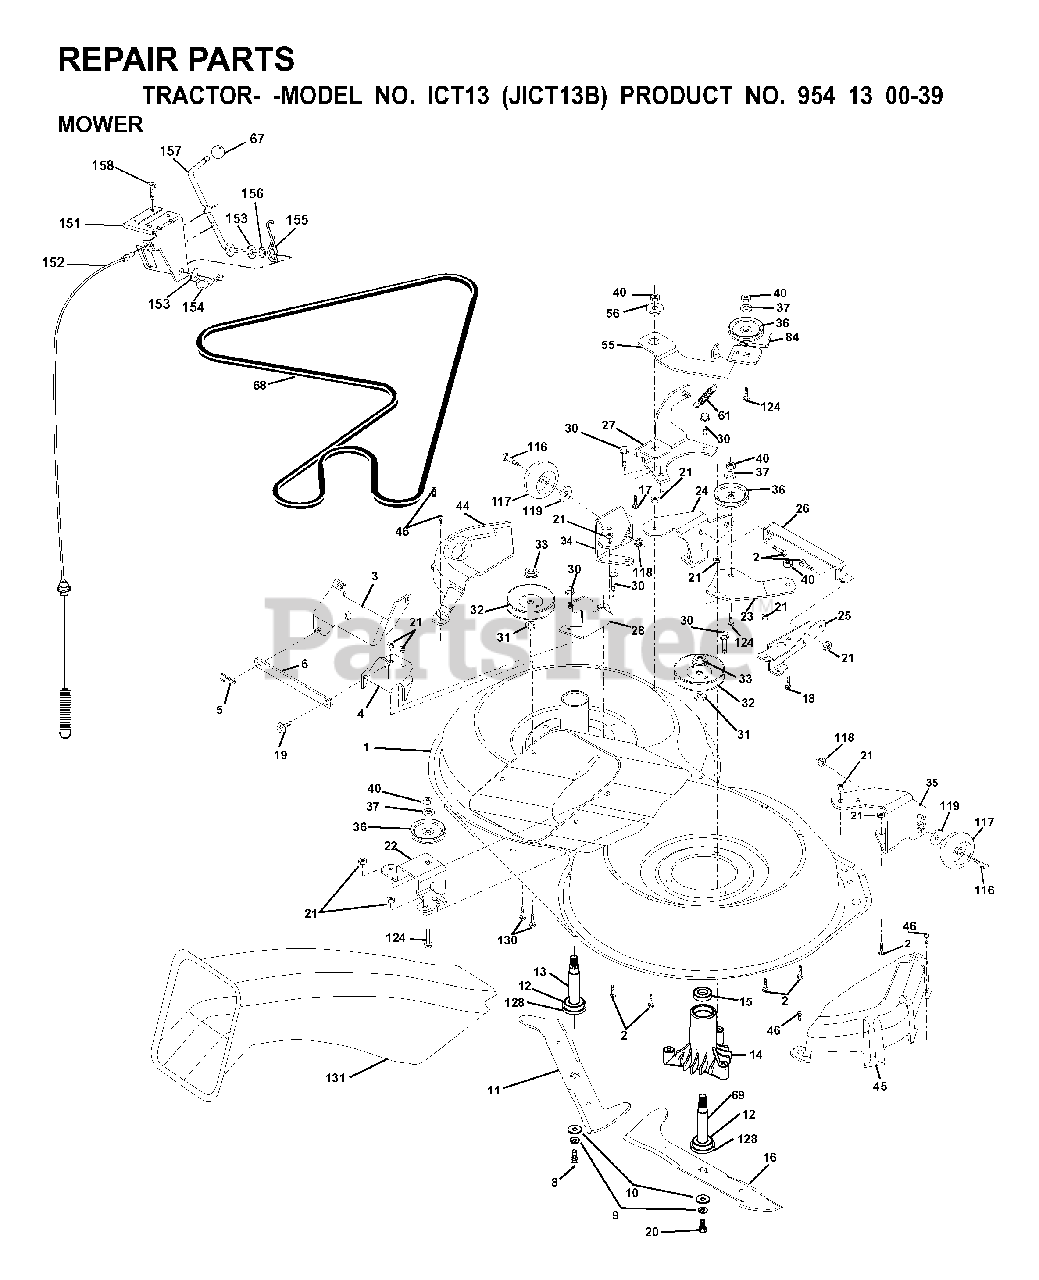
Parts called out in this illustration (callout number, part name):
1	MOWER HOUSING, DECK
2	BOLT
3	BRACKET
5	RETAINER-SPRNG RB
6	BAR SWAY
8	BLADE BOLT
9	LOCKWASHER
10	WASHER.BLADE
11	BLADE-LH 5PT STAR(CTH130)
12	BEARING
13	SHAFT ASM VENT
14	HSG MANDREL
16	BLADE RH 6PT STAR(CTH130)
17	BOLT.3/8-14X1.25
19	BOLT SHD 5/16-18
21	LOCKNUT
24	BRACKET
25	BRACKET
26	BRACE
28	BRACKET
30	SCREW THDROL ROLLING WASHER HD
31	WASHER
32	PULLEY, MANDREL
33	NUT
36	PULLEY.IDLER.4.25
40	LOCKNUT
45	COVER
46	SCREW.1/4-20X5/8
55	ARM IDLER
56	SPACER.RETAINER.MOWER
61	SPRING.TENSION.BELT
69	SHAFT.ASM.W/LWR.BRG.RH.THREAD
84	KEEPER, BELT IDLER
116	BOLT, SHOULDER
117	WHEEL GAGE DONUT
118	LOCKNUT
119	WASHER
124	BOLT.3/8-16X1.50
128	WASHER FELT
131	CHUTE BAGGER
151	BRACKET, CLUTCH CABLE
153	WASHER FLAT 3/8"
154	SPRING RETAINER
155	SPRING RETENTION LEVER
156	SPACER CLUTCH CABLE
158	SCREW LT
